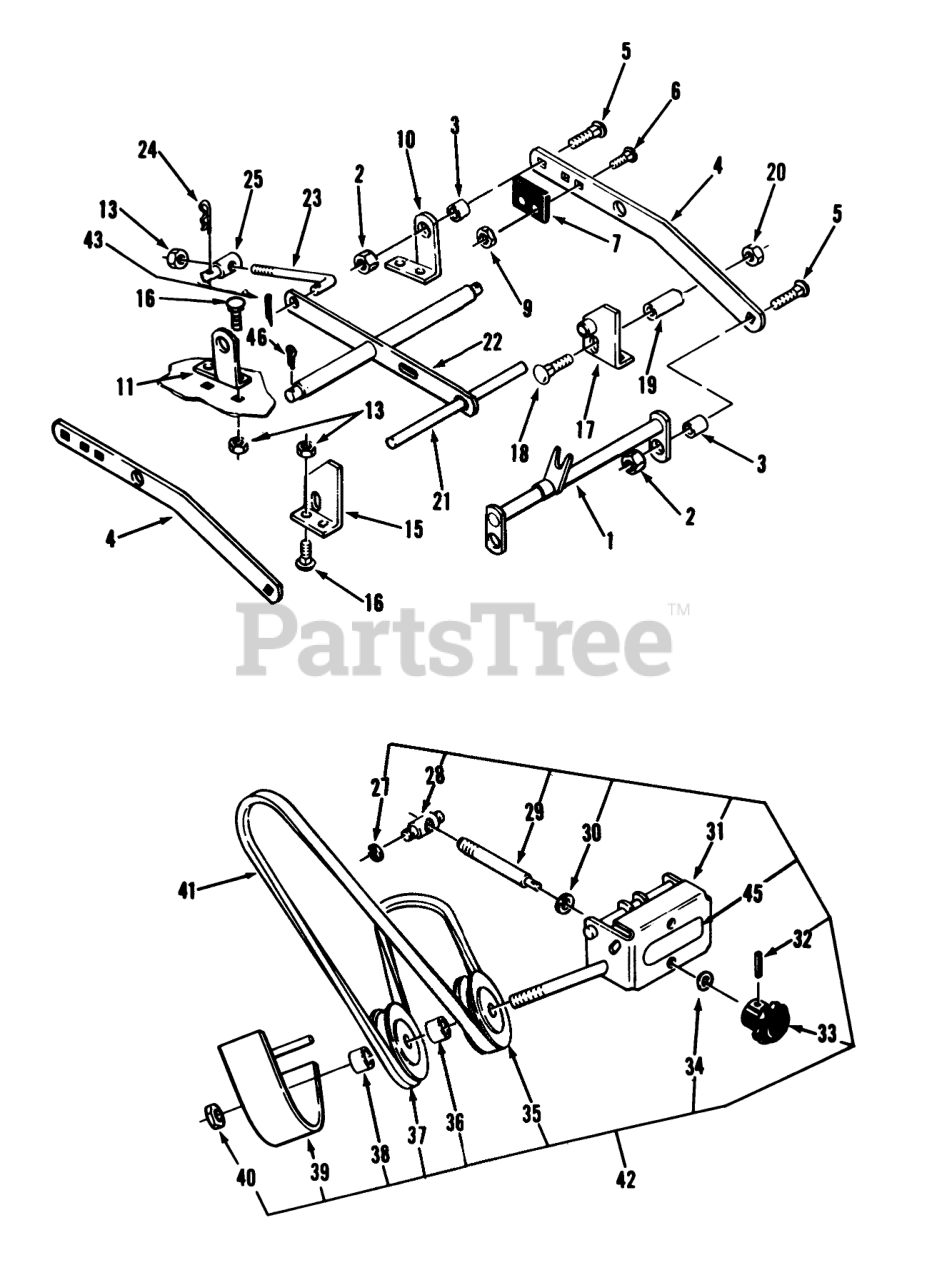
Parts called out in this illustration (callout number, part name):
1	Hitch
2	LOCKNUT-FLANGE
3	SPACER
4	Bar Draft
5	BOLT-CARR
6	SCREW-CARR
7	BUMPER
9	NUT-LOCK, NI
10	LH Rear Bracket
11	Rear Bracket RH
13	NUT-LOCK, NI
15	Front Bracket RH
16	BOLT-CARR
17	Front Bracket LH
18	BOLT-CARR
20	Nut
21	Front Shaft
22	Leveler
23	ROD-LEVEL ADJUST
24	Hairpin
25	TRUNNION-LIFT
27	RING-RETAINING
28	TRUNNION-DOUBLE
29	ROD ADJ
30	WASHER-FLAT
31	Front Support
32	PIN-ROLL
33	KNOB-ADJUSTMENT
34	WASHER-SPRING
35	Pulley-V
36	SPACER
37	PULLEY-FLAT IDLER
38	SPACER-OUTER
39	Belt Cover
40	Nut
41	V-BELT
42	Assembly-Idler, Front (Incl. Ref. #27-40 & 45)
43	PIN-COTTER
45	Decal-Attac-O-Matic
46	PIN-COTTER
